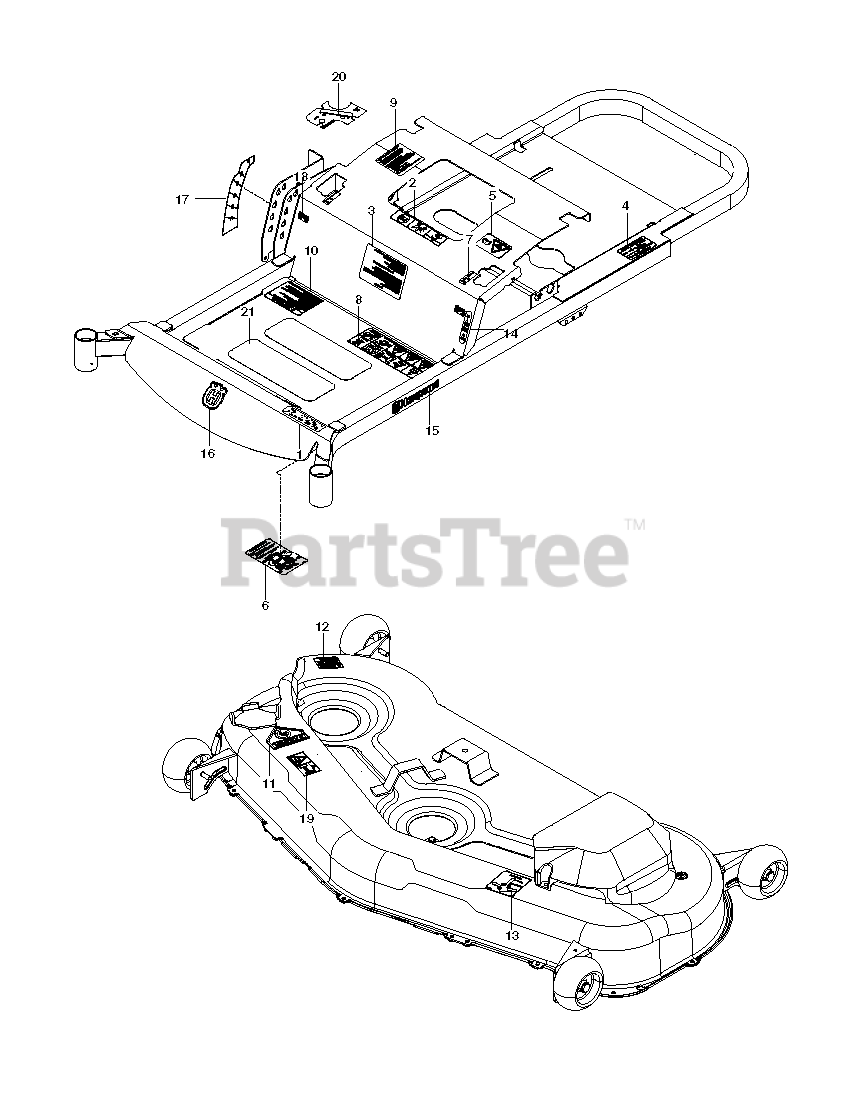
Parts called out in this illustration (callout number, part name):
1	DECAL, RZ5424
2	EURO DECAL-BATTERY WARNIN6
3	DECAL, START
4	DECAL, DO NOT TOW
5	DECAL, EXITING MOWER
6	DECAL, SERVICE
7	DECAL, MOTION CONTROL
8	DECAL, SAFETY WARNING
9	DECAL, CUSTOMER RESPNSIBILITY
10	DECAL, WARNING
11	DECAL, CPSC
12	DECAL, CAUTION
13	DECAL, BELT ROUTING
14	DECAL, PARK BRAKE
15	RP.DECAL.BADGE.170MM.TEXTLOGO
16	DECAL.AUGER.HUSQ.CROWN.SNOW
17	DECAL, DECK HEIGHT, HUSQ
18	DECAL, F.S.T.
19	DECAL, EURO SEVERING
20	DECAL, CTRL PANEL, HUSQ
21	ANTI-SKID PAD
